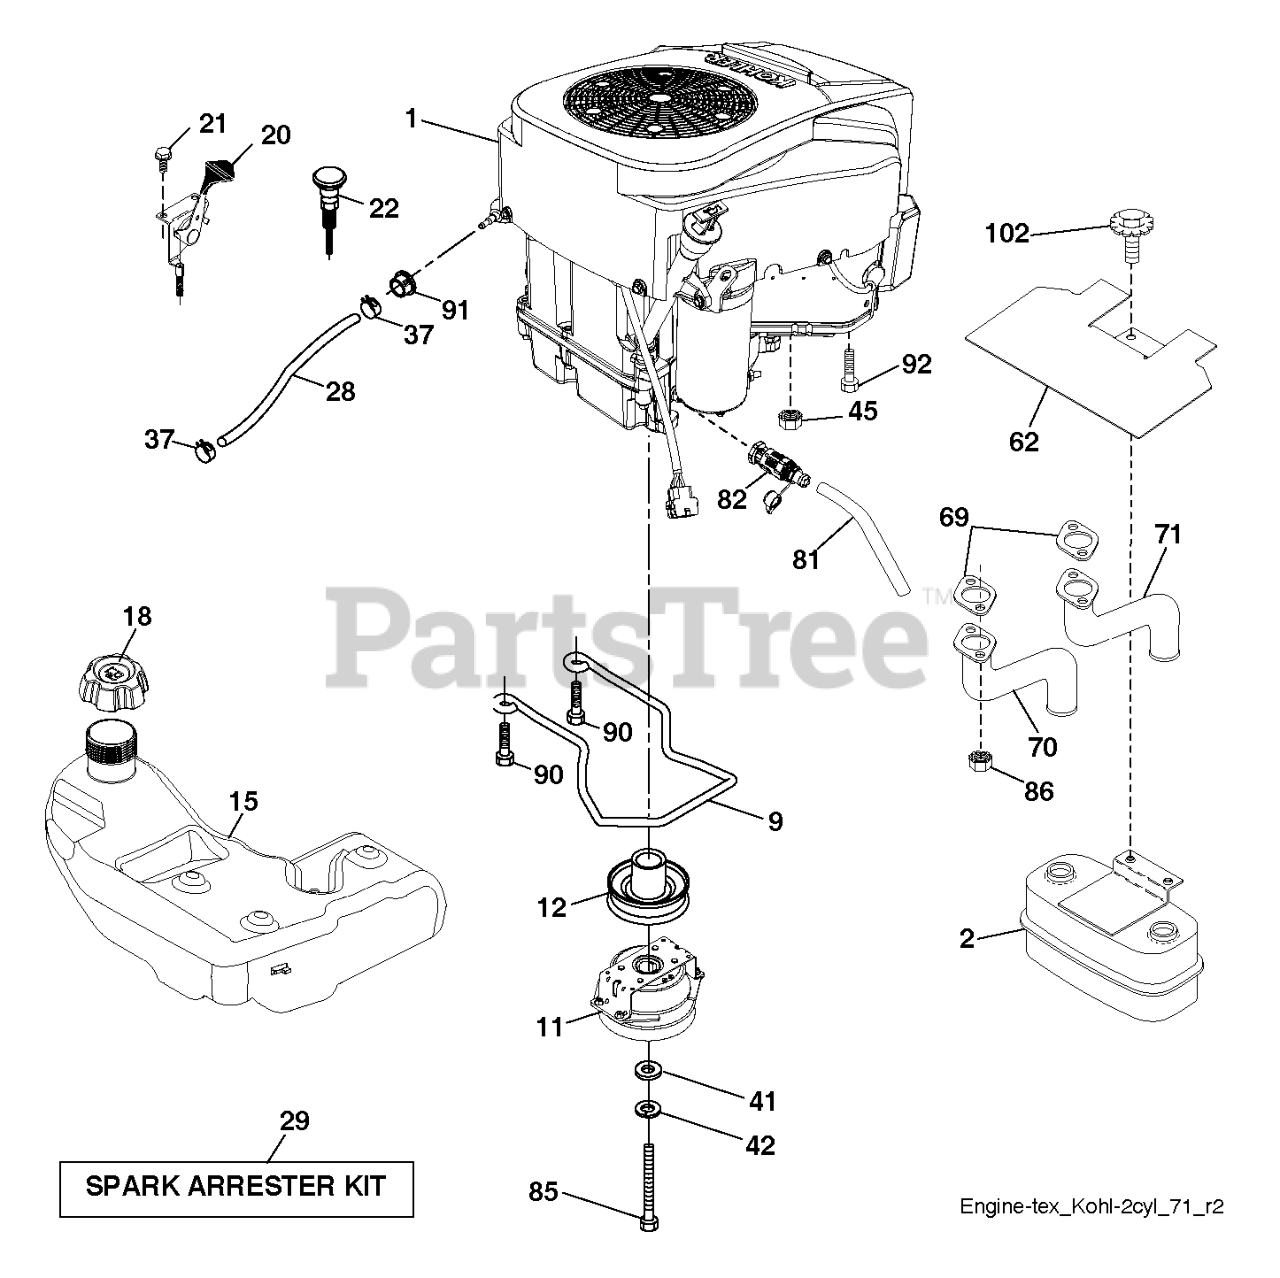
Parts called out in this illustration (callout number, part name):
2	MUFFLER.ASM.TWIN.MNTG.BRACKET
9	KEEPER.BELT.ENG.4.25"2.BLT.431
11	CLUTCH.OGURA.5.0PD.GT1.5A-EH01
12	PULLEY ENGINE
15	TANK.ASM.FUEL.4GAL.EPA.17
18	FUEL CAP
18	CAP ASSY FUEL 3" GRAY
20	THROTTLE CONTROL
21	SCREW.#10 X 0.750.BOS
22	CONTROL.CHOKE.ERGO.PUSH-IN.BLA
28	HOSE.1/4".LOW.PERM.FUEL.LN.60"
29	KIT.SPARK ARRESTOR 794945 B&S
37	HOSE CLAMP
42	WASHER 7/16 LOCK
45	NUT
62	SHIELD.HEAT.MUFFLER
69	GASKET.EXHAUST.KOHL.CV18-CV26
70	PIPE.EXHAUST.LH.CV18/20
71	PIPE.EXHAUST.RH.CV18/20
81	TUBE, DRAIN OIL ASM.
82	VALUE.OIL.DRAIN
85	BOLT.HEX.7/16-20X3.GR5.YELLOW
86	NUT.HEX.FLANGE.TOPLOCK
90	SCREW 3/8-16X1
91	BUSHING.1.375OD
92	SCREW 3/8-16X1
102	SCREW
